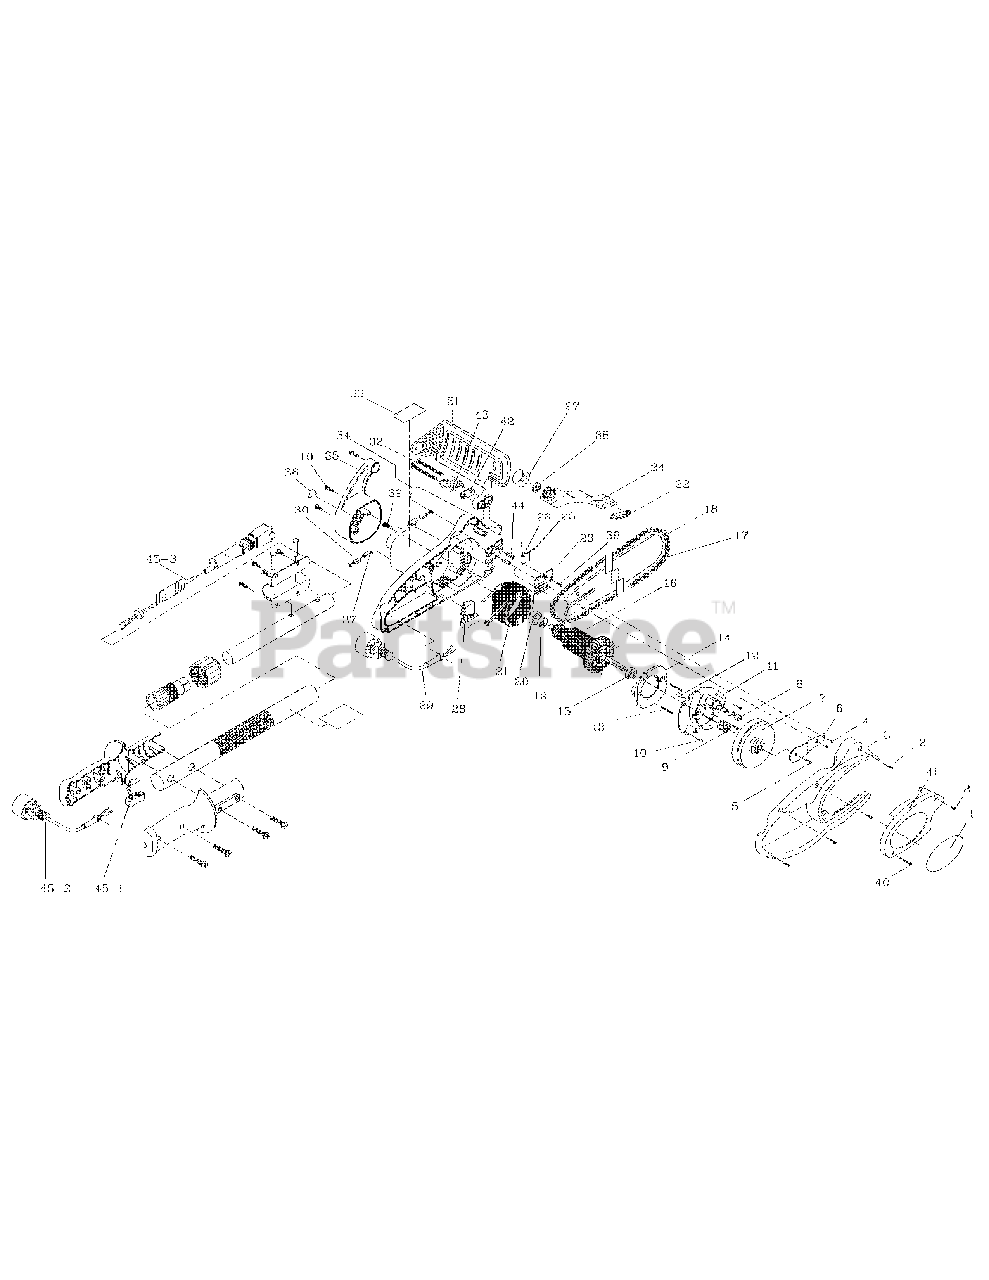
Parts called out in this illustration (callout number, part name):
3	HOUSING ( R)
5	FIXED SCREW
6	SPROCKET SUPPORT
7	SPROCKET-GEAR
8	ROLLER BRARING
9	MOTOR GEAR
11	MOTOR COYER ASSEMBLY
12	RUNNER STICK
14	WIND GUIDE
16	ARMATURE ASS'Y
17	10" CHAIN
20	ANTI-VIBRATILLAGE PAD
21	FIELD ASS'Y
22	ANTI-SPILLAGE PAD
23	ADJUSTING PLATE
25	REGULATION SCREW
26	REGULATION CAP
28	LOCK-OFF SWITCH
29	POWER CORED
31	FRONT-HAND GUARD
33	WARNING TAG
34	HOUSING (L)
35	REAR COVER
37	BRUSH SETS
38	ANTI-SPILLAGE
41	LEFR-CASE
42	MOUNT PLATE
45	INNER PIPE ASS'Y
45-2	POWER CORED
